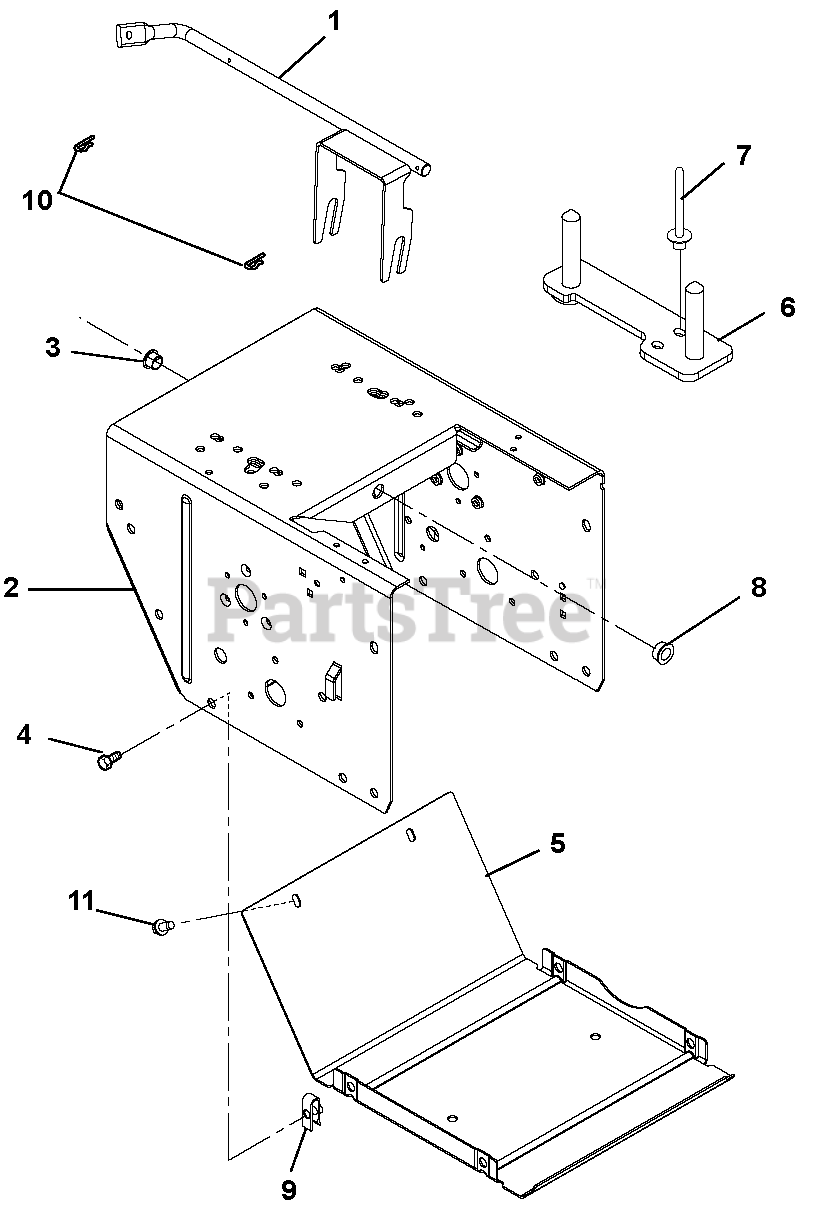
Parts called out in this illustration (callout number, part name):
1	ARM, SHIFT-WELDMENT
2	PRO FRAME, MAIN
3	BUSHING, POLYLINER-.50 SPLIT
4	BLT-HEX .25-20X.75 HWH YZ GR5
5	COVER, BOTTOM
6	STRAP, ENGINE BOLT-LARGE BRIGG
7	RVT-POP .187 YZ
8	BUSHING, POLYLINER-.50 SNAPIN
9	NUT-RTNR .25-20X.56
10	CLIP, SPRING
11	SCR-TAP .25-20X.50 HWH TR YWZ
